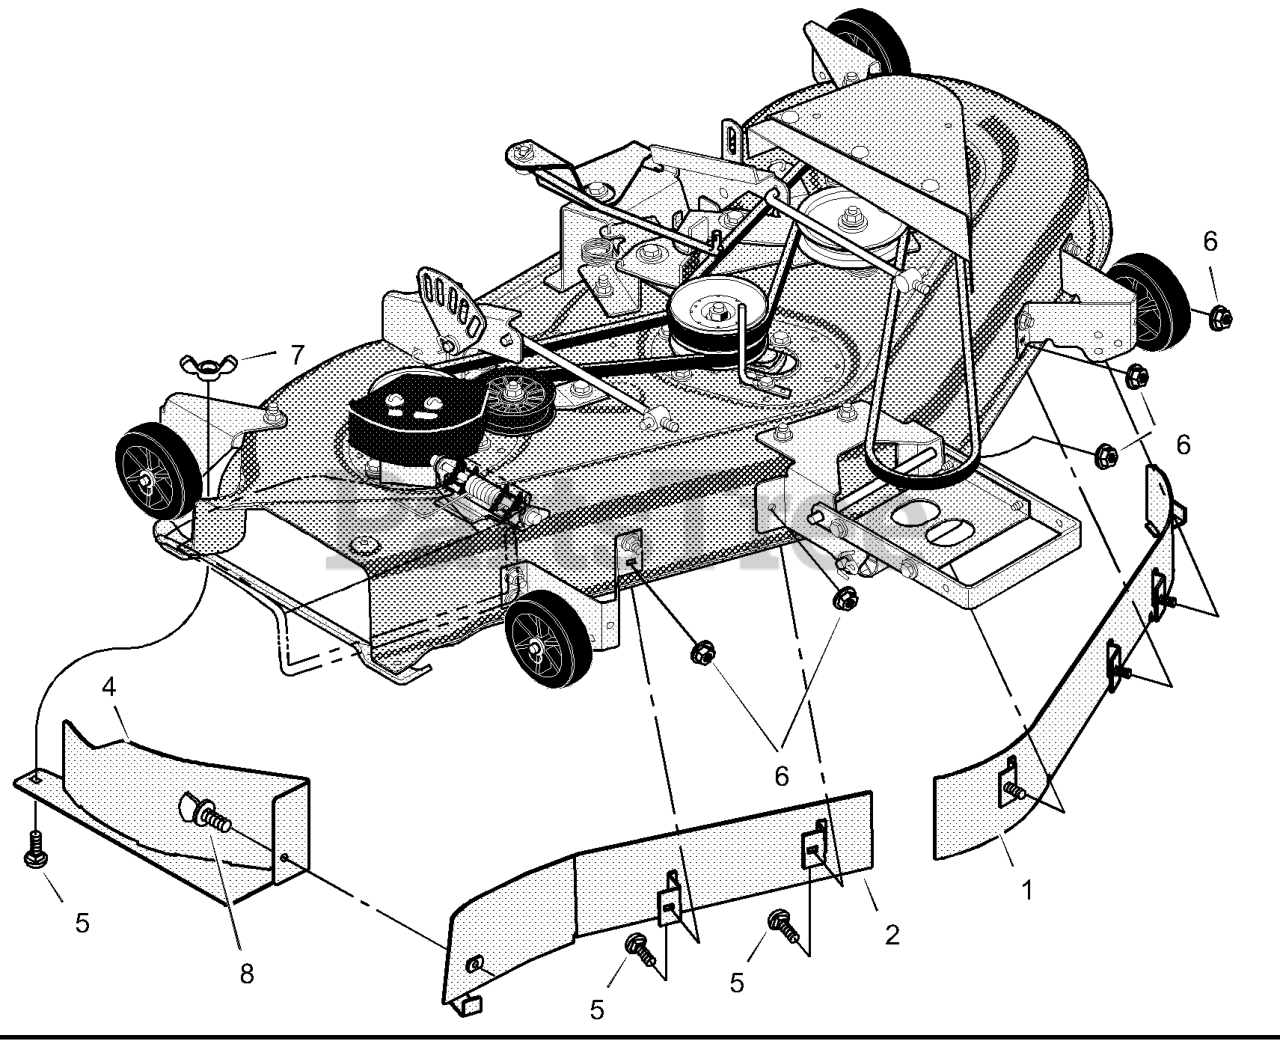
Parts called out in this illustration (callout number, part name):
1	Baffle, Left
2	Baffle, Right
4	Plate, Mulcher
5	Bolt, Carriage
6	Nut, Flange
7	Wingnut
8	Screw, Thumb
